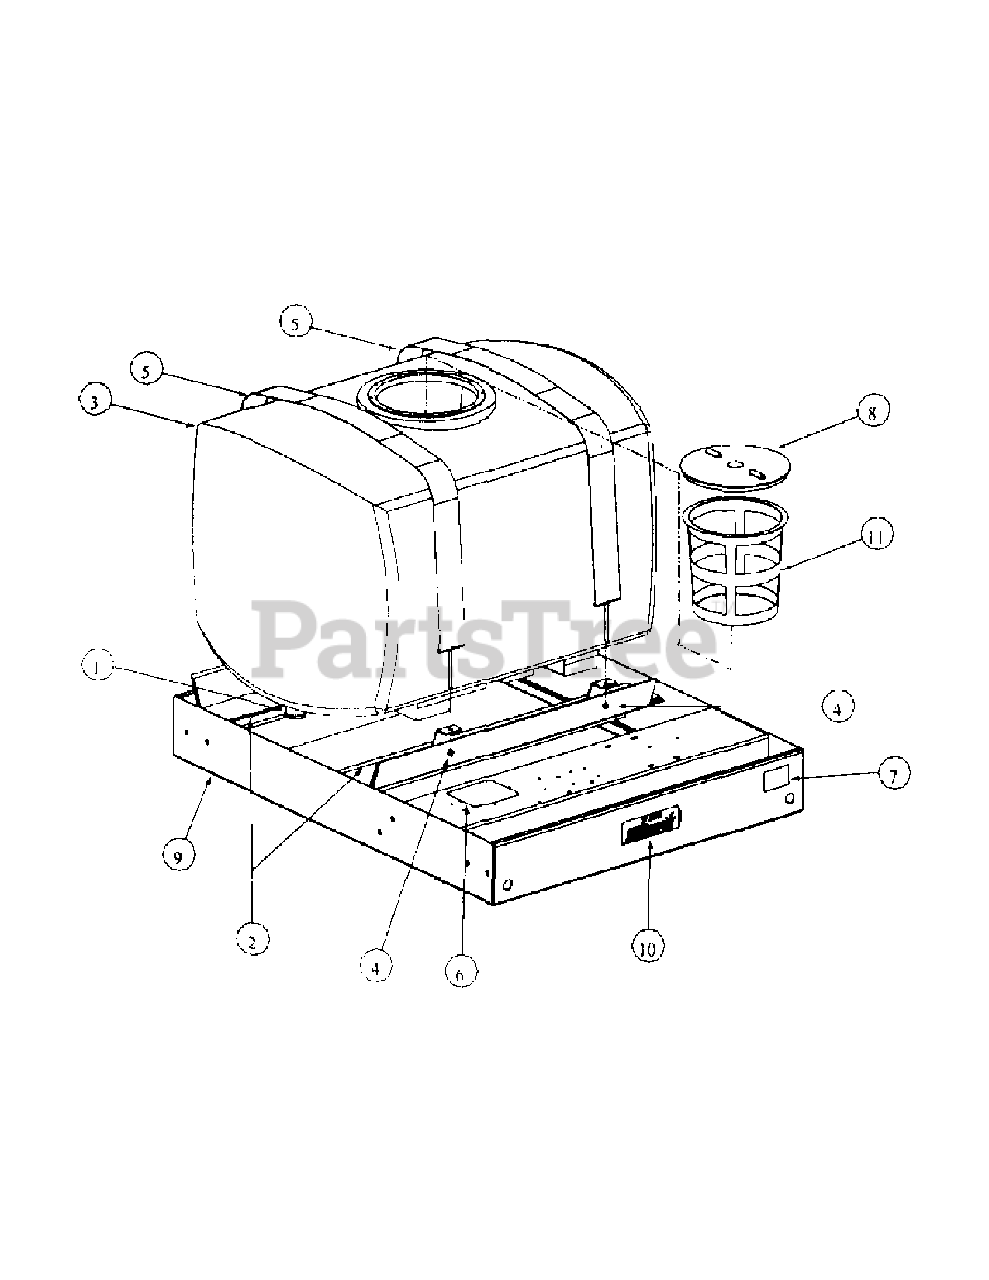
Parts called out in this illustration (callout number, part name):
1	Adapter, PVC, 1.25 NPT, 1 NPT
2	Foam, Adhesive Backed, 4" x 1/4" by ft
3	100 Gal. Poly Tank w/Lid
4	Nut, Nylock 5/16 - 18
5	Tank Strap Assembly
6	Decal Safety Procedures
7	Decal "Made in America"
8	Tank Lid
9	Main Frame Assembly
10	Decal, "SY 100, 2-1/4" x 7"
11	Strainer Basket, 10"
